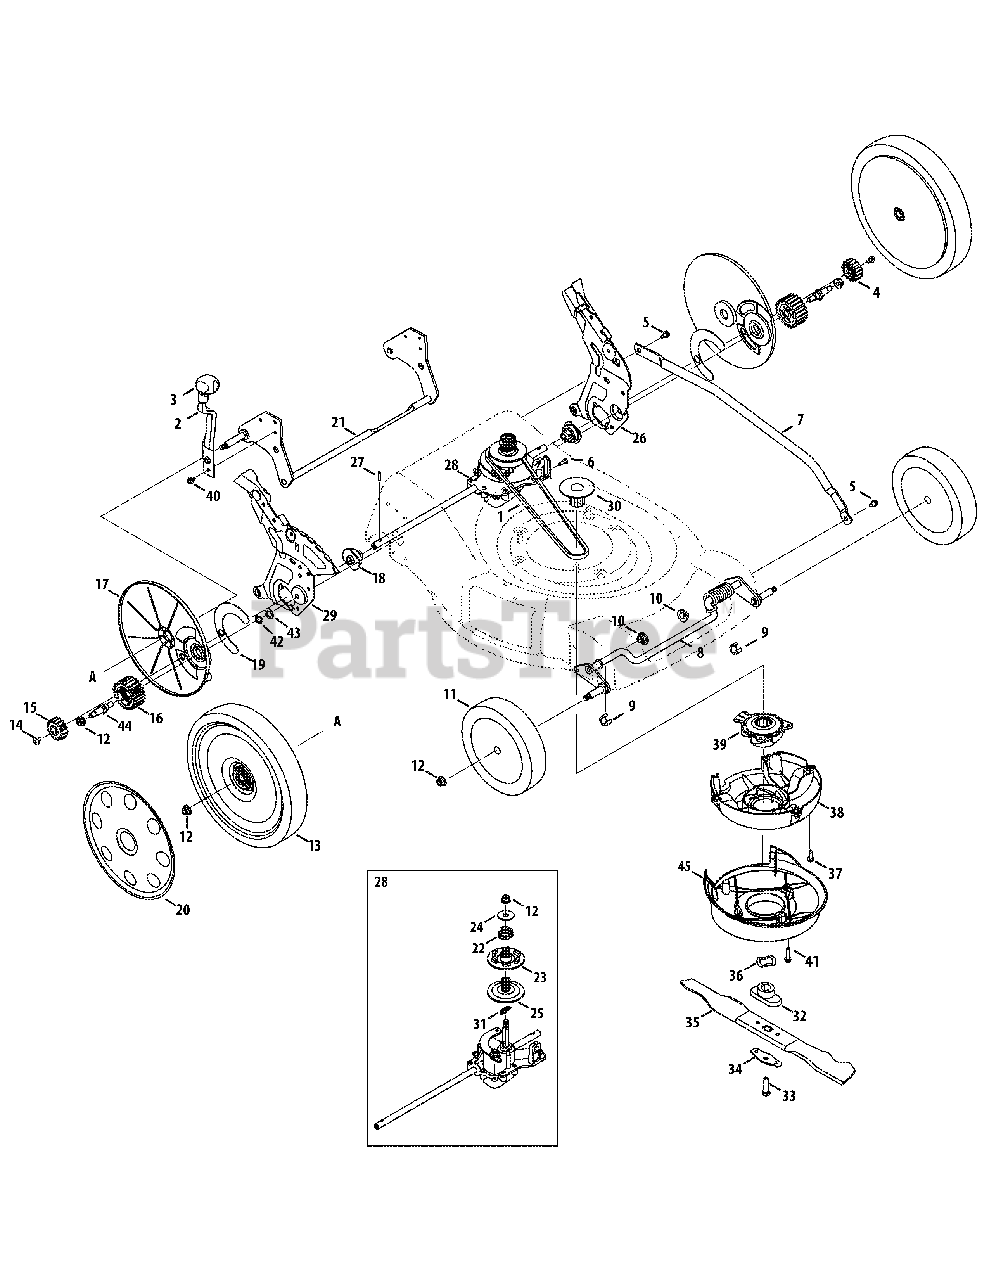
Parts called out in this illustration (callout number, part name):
1	V-Belt
2	Spring Lever
3	Height Adjuster Knob
4	Spur Gear, 16T - LH
5	Shldr. Screw, 1/4-20 x 0.50
6	Screw, #12-16 x .750
10	Split Hex Flange Bearing
11	Front Wheel
12	Flange Lock Nut, 3/8-16
13	Rear Wheel
14	Screw, 1/4-20 x .39
15	Spur Gear, 16T - RH
16	Gear, Spur, 23T
17	Wheel Dust Cover
18	Bearing Assembly
19	Dust Cover Seal Plate
23	Upper Pulley
24	Flat Washer, .442 x 1.38 x .060
25	Lower Pulley
27	Dowel Pin
28	Transmission Assembly
30	Pulley, Half
31	Extension Spring
32	Blade Adapter
33	Screw, 3/8-24 x 1.50
34	Blade Bell Support
35	21" Mulching Blade
36	Washer, Wave, 1.5 x 1.0 x .029
37	TT Screw, 1/4-20 x .500
38	Engine Baffle
39	Lower Pulley Assembly
40	Screw, TT, 1/4-20 x .375
41	Screw, 1/4-15 x 1.00
42	Washer, Wave, .510 x .750 x .017
43	Washer, Flat, .531 x .875 x .060
44	Shaft., .500 Dia. X 2.456
44	Spacer,.499 x .685 x .380
44	Spacer, .499 x .860 x .380
